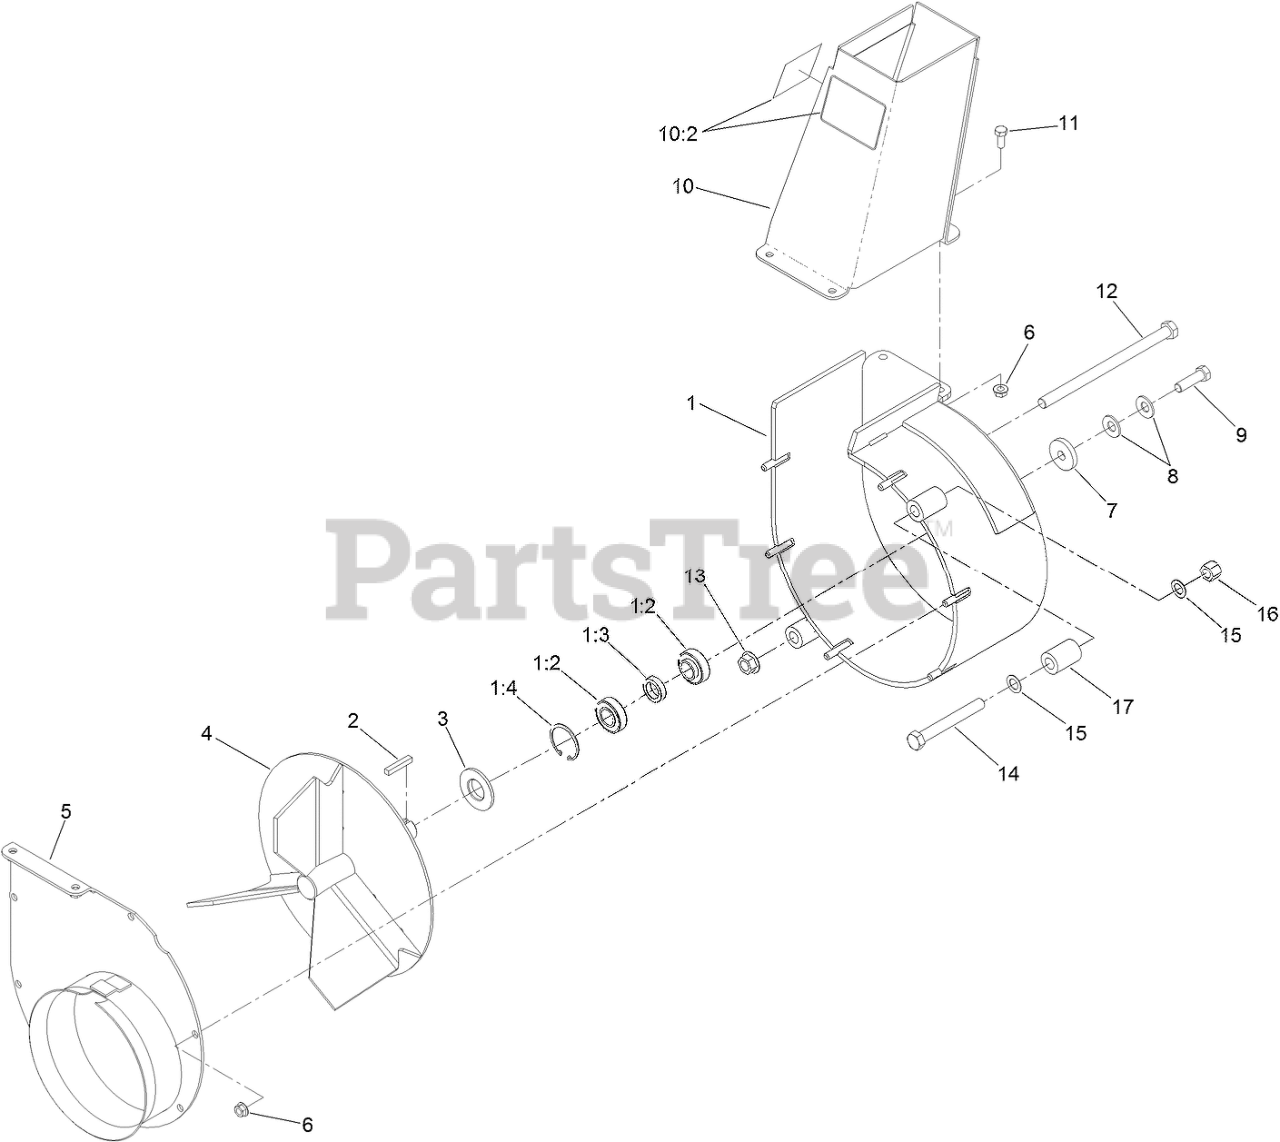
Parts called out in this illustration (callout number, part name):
1	HOUSING ASM
1:2	BEARING-BALL
1:3	SPACER-BEARING
1:4	RING-SNAP
2	KEY-SQUARE
3	SPACER-BLOWER
4	IMPELLER-3 BLADE
5	COVER-BLOWER
7	WASHER-CLUTCH
8	WASHER-SPRING
9	SCREW-HH
10	DISCHARGE CHUTE ASM
10:2	DECAL-DANGER, IMPELLER
11	SCREW-HH
12	SCREW-HH
14	SCREW-HH
15	WASHER-THRUST
16	NUT-LOCK, NI
17	SPACER-MOUNT
